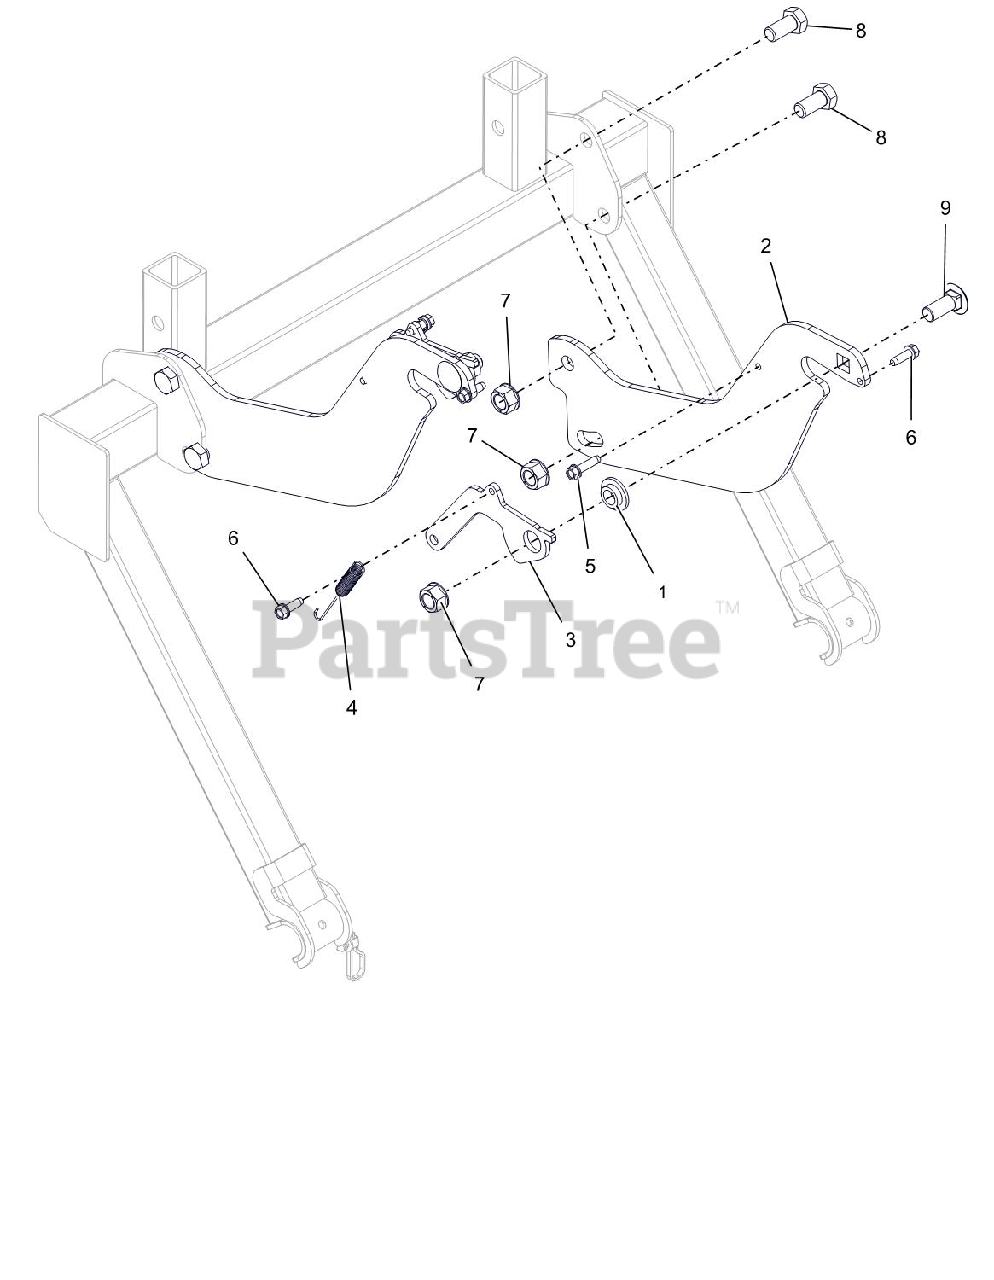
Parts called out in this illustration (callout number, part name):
1	BSHG-FLG .515X.750X.395X1.120
2	LATCH, BAGGER MTG ARMS
3	BAGGER, LATCH
4	SG-TENS .043X.44X3.31 WLD 5.8
5	@SCR-TAP .25-20X1.00 HWH TR YZ
6	SCR-TAP-PM .25-20X.75 TR YWZ
7	NUT-LK-TOP-FLG .50-13 YWZC
8	@BLT-HEX .50-13X1.00 GR5 YWZC
9	@BLT-RDHDSQNK .50-13X1.25 G5YZ
